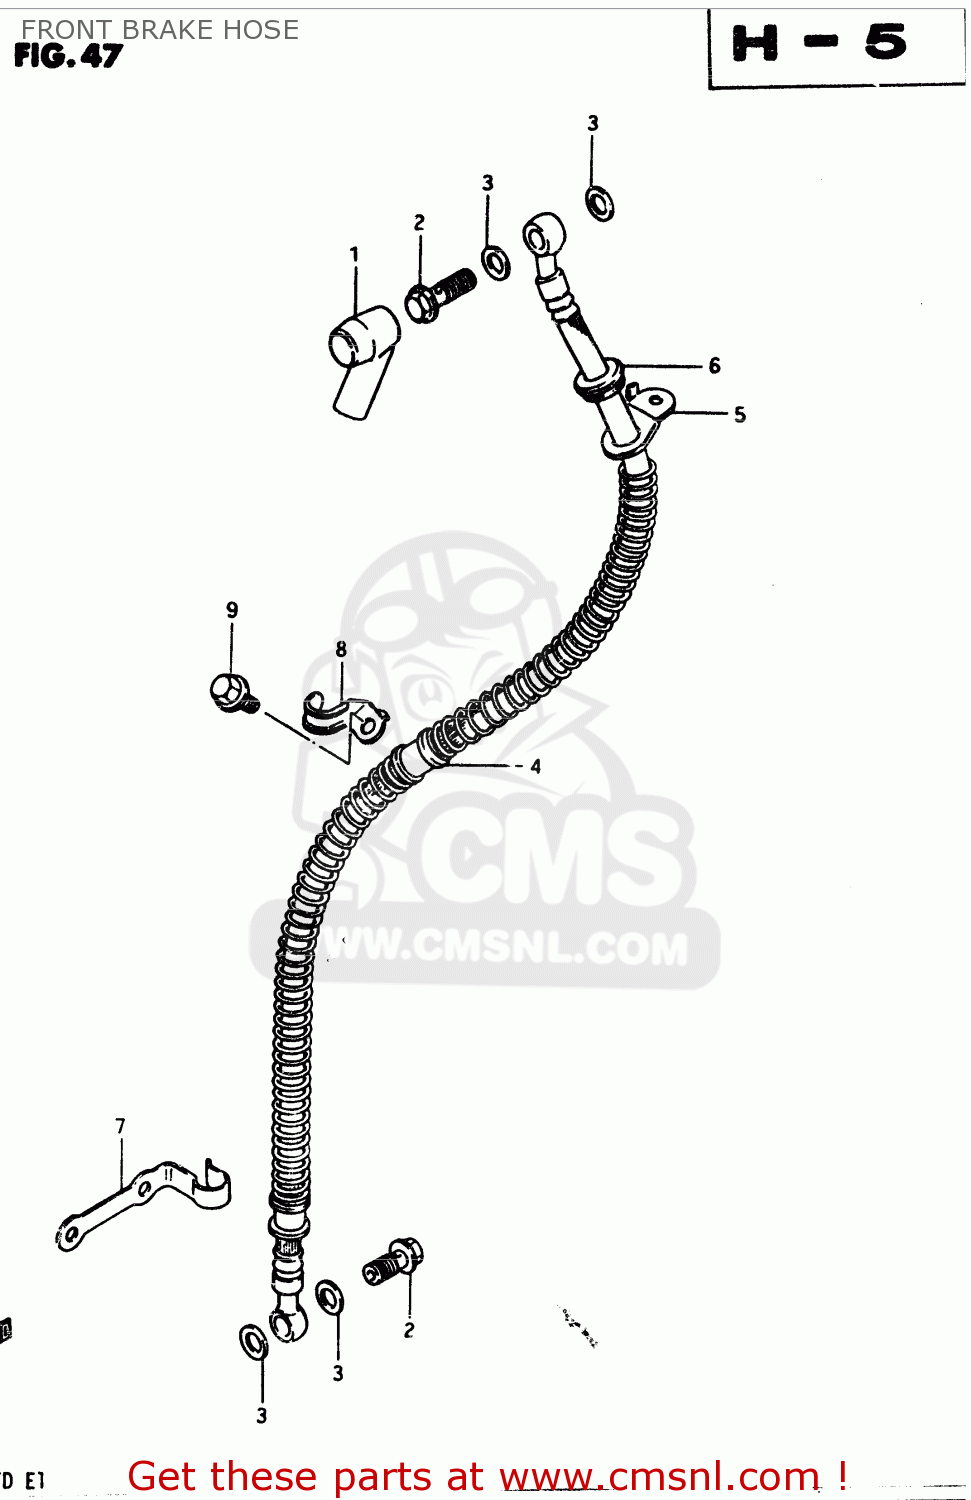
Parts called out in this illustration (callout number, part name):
1	BOOT,MASTER CYLINDER
2	BOLT UNION
3	WASHER
4	HOSE,FRONT BRAKE
5	GUIDE,BRAKE HOSE
6	GROMMET
7	GUIDE,BRAKE HOSE NO.2
8	GUIDE,BRAKE HOSE NO.3
9	BOLT
